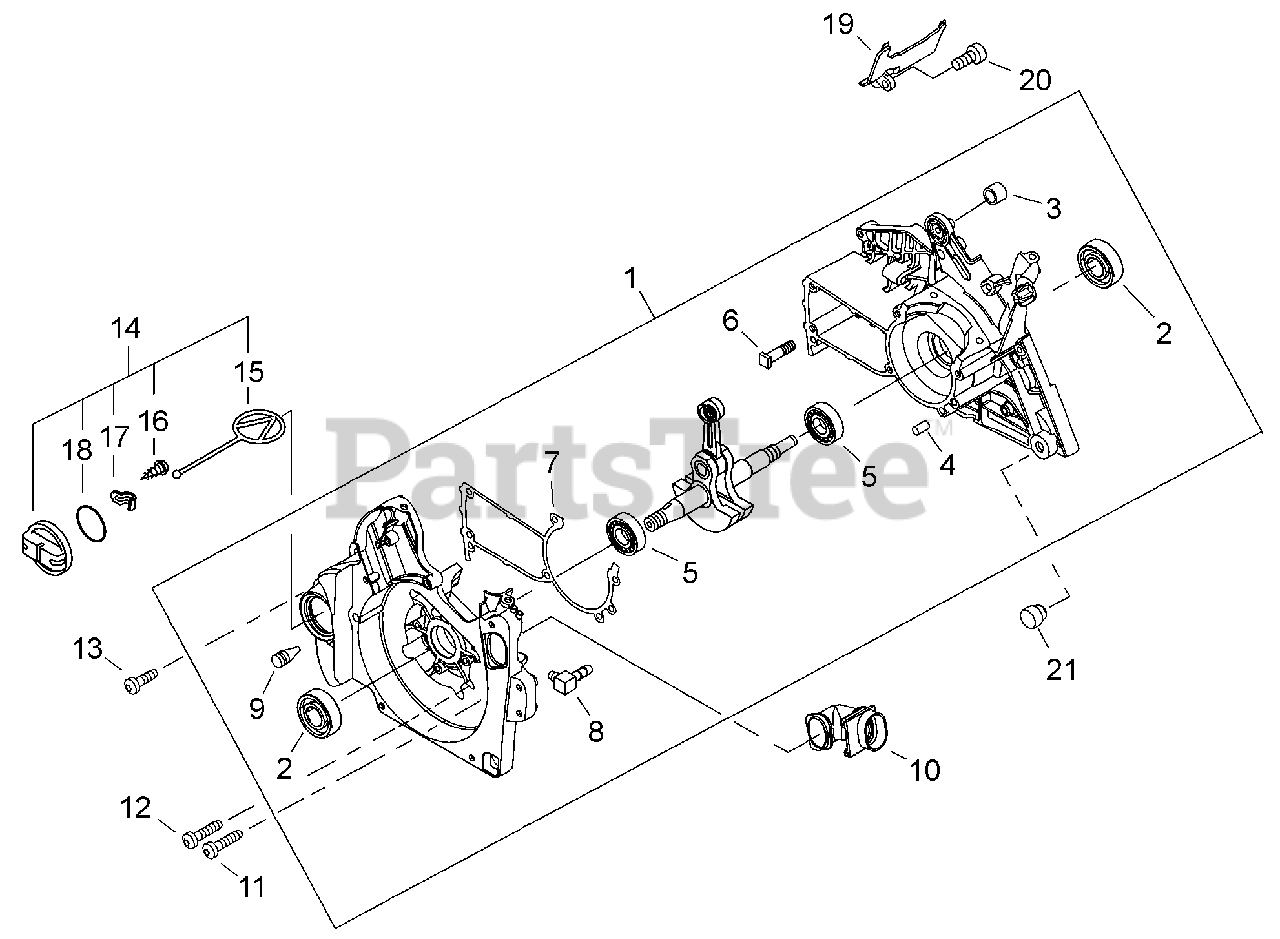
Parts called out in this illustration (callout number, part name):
1	CRANKCASE KIT
2	SEAL, OIL 15
3	SPACER 12×10×T: 1.0
4	PIN, LOCATING 5×10
5	BEARING, BALL 6202
6	BOLT, STUD M8×1.25×34.5
7	GASKET, CRANKCASE
8	CONNECTOR, PIPE
9	VENT ASSY
10	PIPE, AIR INTAKE
11	BOLT, TORX 5×25
12	BOLT, TORX 5×35
13	BOLT, TORX 5×20
14	CAP ASSY, OIL
15	CONNECTOR, CAP L= 60mm
16	SCREW, TAPPING 3×8
17	RETAINER, CONNECTOR
18	O-RING 28
19	GUIDE, AIR
20	BOLT, TORX 5×16
21	CUSHION
